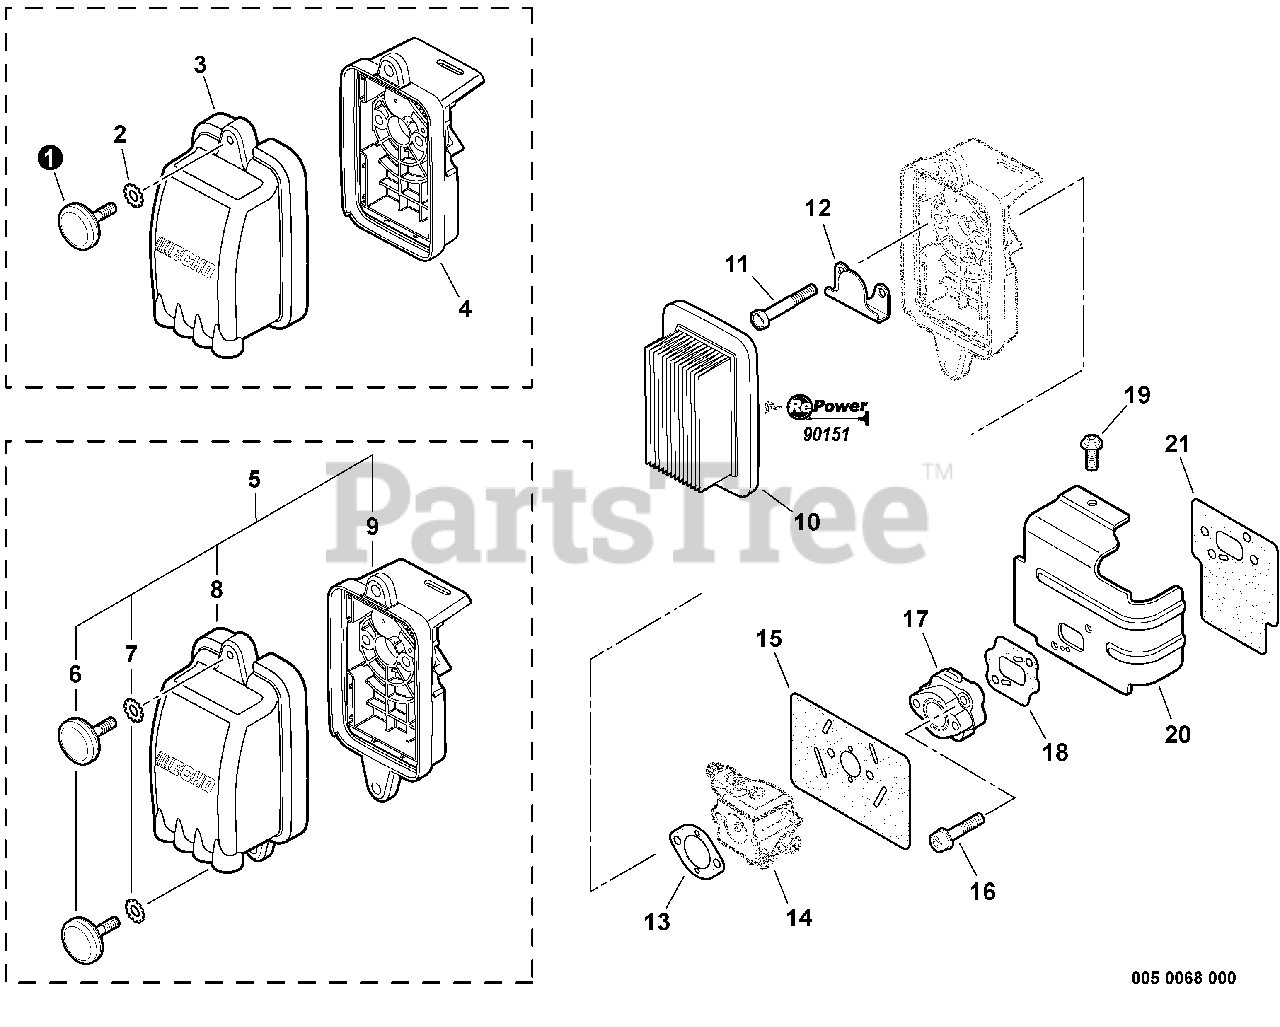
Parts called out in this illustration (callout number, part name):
1	THUMBSCREW
2	LOCKWASHER
3	COVER, AIR FILTER
4	AIR FILTER CASE ASSY
5	AIR CLEANER KIT
6	THUMBSCREW
7	LOCKWASHER
8	COVER, AIR FILTER
9	AIR FILTER CASE ASSY
10	FILTER, AIR
11	SCREW - 5X60
12	PLATE, PREVENT
13	GASKET, INTAKE
14	CARBURETOR
15	GASKET, INTAKE
16	SCREW - 5X25
17	INSULATOR, INTAKE
18	GASKET, INTAKE
19	SCREW - 5X10
20	COVER, CYLINDER - INTAKE
21	SHIELD, INTAKE
22	RePower TUNE-UP KIT
